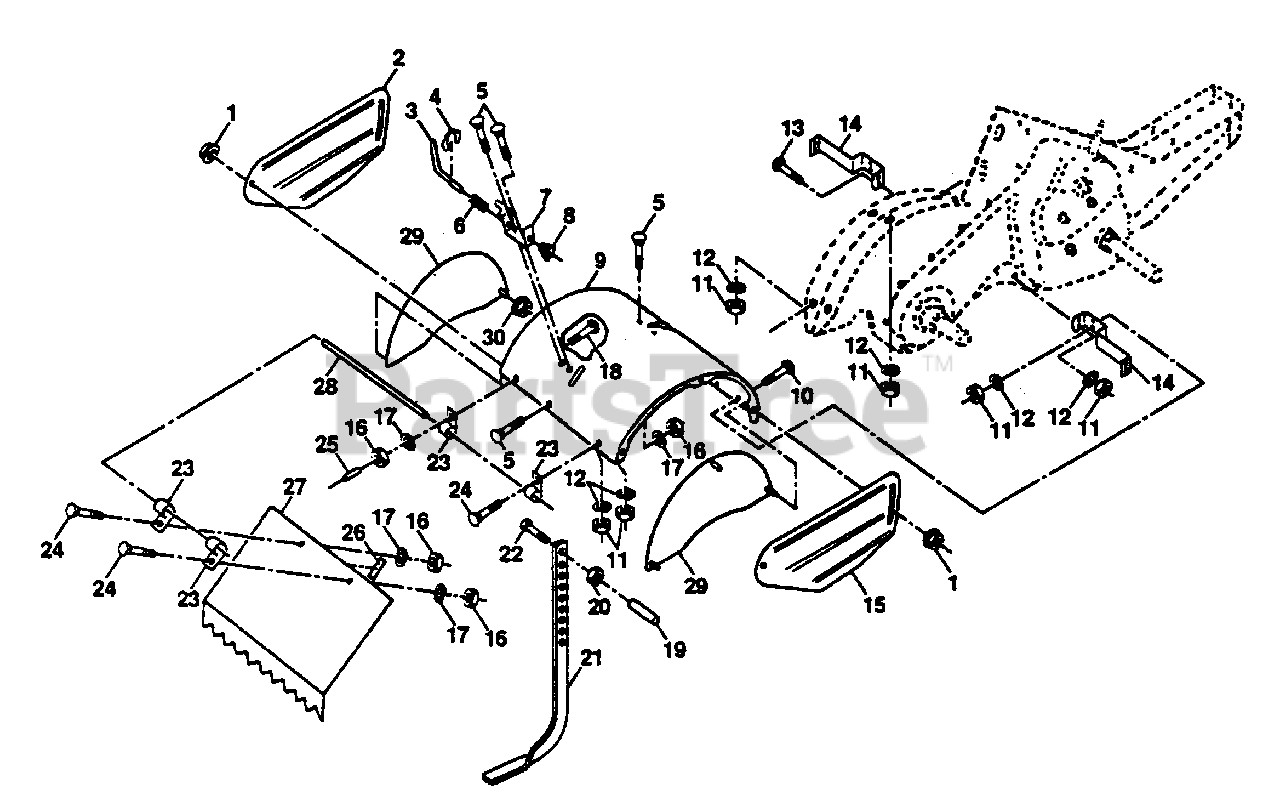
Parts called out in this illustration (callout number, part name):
1	Nut, Flange 5/16-18 (AYP part number)
2	Shield, Side, Outer L. H. (AYP part number)
3	Pin, Stake, Depth (AYP part number)
4	Ring, Klip (AYP part number)
5	Bolt, Carriage 5/16-18 x 3/4 Gr. 5
6	Spring (AYP part number)
7	Bracket, Latch (AYP part number)
8	Spring, Depth Stake (AYP part number)
9	Shield, Tine (AYP part number)
10	Bolt, Carriage 5/16-18 UNC x 1 (AYP part number)
11	Nut, Hex 5/16-18 (AYP part number)
12	Washer, Lock 5/16 (AYP part number)
13	Bolt, Carriage 5/16-18 x 1-1/4 (AYP part number)
14	Bracket, Shield Tine (AYP part number)
15	Shield, Side, Outer R.H. (AYP part number)
16	Nut, Hex 1/4-20 (AYP part number)
17	Washer, Lock 1/4 (AYP part number)
18	Bolt, Carriage 1/4-20 x 1-1/4 Gr. 5 (AYP part number)
19	Grip (AYP part number)
20	Nut, Hex 3/8-16 (AYP part number)
21	Stake, Depth (AYP part number)
22	Bolt, Hex 3/8-16 x 2 (AYP part number)
23	Hinge (AYP part number)
24	Bolt, Carriage 1/4-20 x 1/2 Gr. 5 (AYP part number)
25	Cap, Vinyl (AYP part number)
26	Pad, Idler (AYP part number)
27	Shield, Leveling (AYP part number)
28	Pin, Hinge (AYP part number)
29	Shield, Side (AYP part number)
30	Locknut, Flange 5/16-18 (AYP part number)
